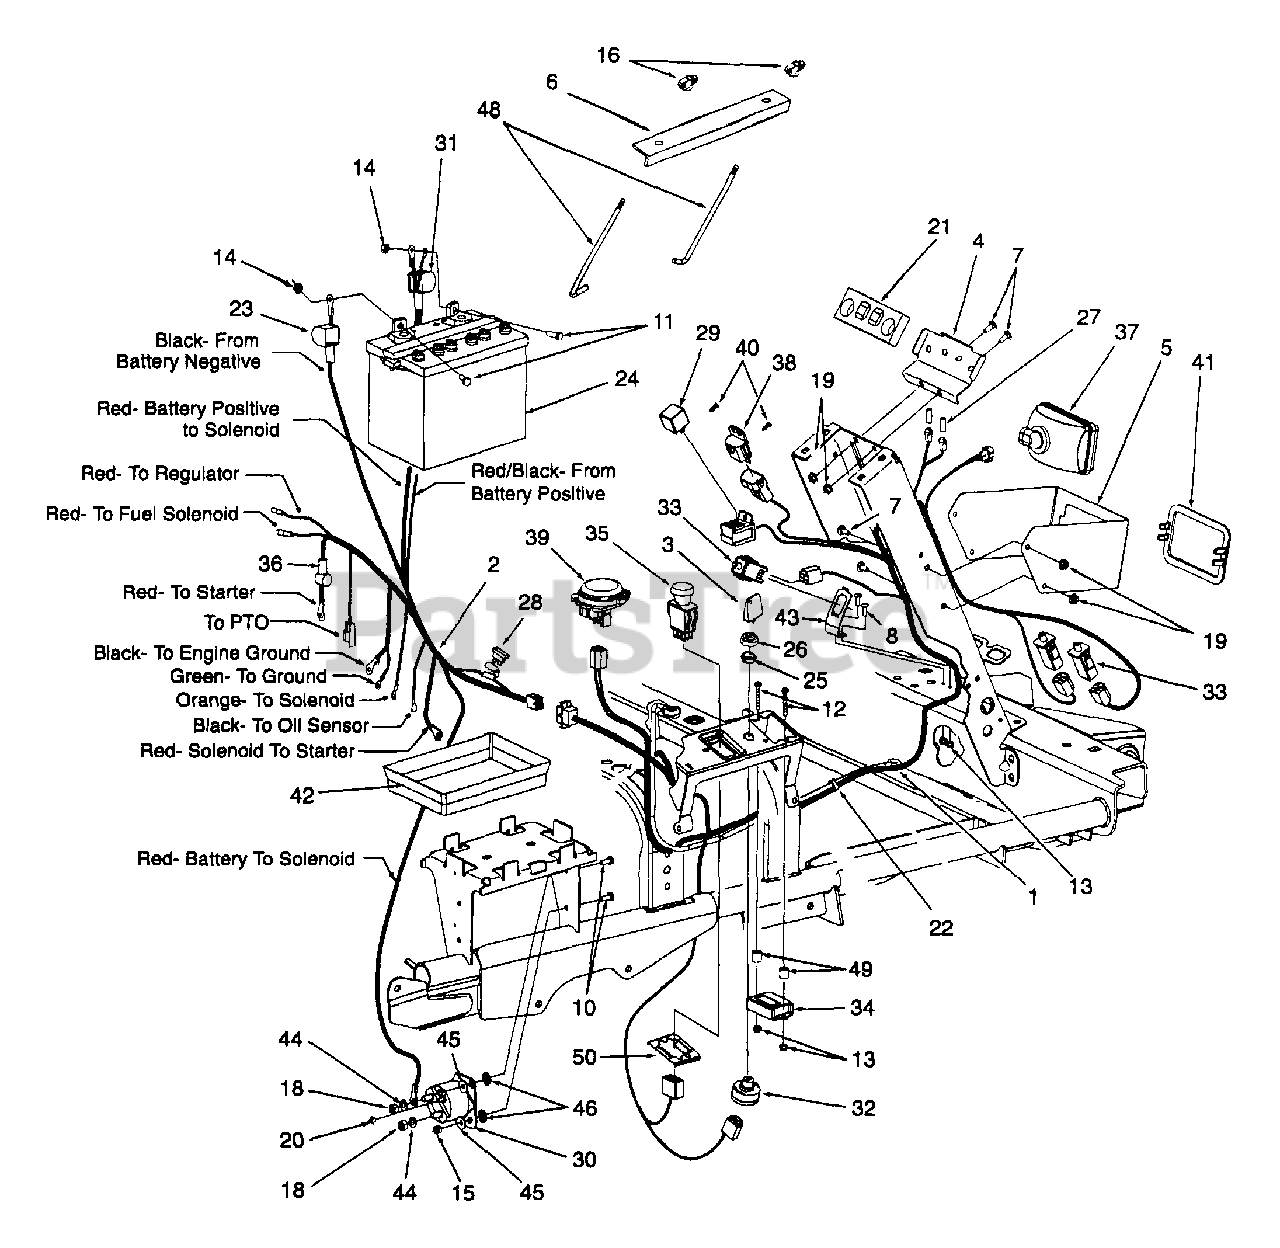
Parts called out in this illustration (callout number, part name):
1	Wire Harness, Main
2	Wire Harness, Engine
3	Key, Ignition
6	Strip, Battery Retainer
7	Bolt, Carriage, 1/4-20 x .62
8	Screw, Machine, #10-24 x 5/8
10	Screw, Hex Cap, 1/4-20 x .62 GR5
11	Screw, Hex Cap, 1/4-20 x .75 GR5
12	Screw, Pan Hd Cutting, #10-24
13	Nut, Hex Insert Lock, #10-24
14	Nut, Hex Sems, 1/4-20
15	Nut, Hex Center Lock, 1/4-20
16	Nut, Nylon Wing, 1/4-20
18	Nut, Hex, 5/16-18
19	Nut, Hex Flange Lock, 1/4-20
20	Nut, Hex Sems, #10-32
21	Foam Protector, Indicator Light
23	Cover, Battery Terminal - Black
24	Battery
25	Nut, Ignition Switch, 5/8-32
26	Cap, Ignition Switch
27	Bulb, Indicator
28	Fuse, Mini, 20Amp
29	Relay
30	Solenoid Switch
31	Cover, Battery Terminal - Red
32	Switch, Ignition
33	Switch, Plunger Safety
34	Hourmeter/Tachometer
35	Switch, PTO
36	Cover, Terminal - Red
37	Headlight Assembly
38	Sensor, Voltage
39	Switch, Seat
40	Retainer, Ratcheet
41	Bezel, Headlight
42	Tray, Battery
43	Spring, Switch Mounting
44	Washer, Lock, 5/16
45	Washer, Bell, .265 x .75 x .062
46	Washer, Int./Ext. Lock, 1/4 ID
48	Rod, Battery Retainer
49	Spacer, .315 x .50 x .52
50	Bracket, PTO Switch Retainer
